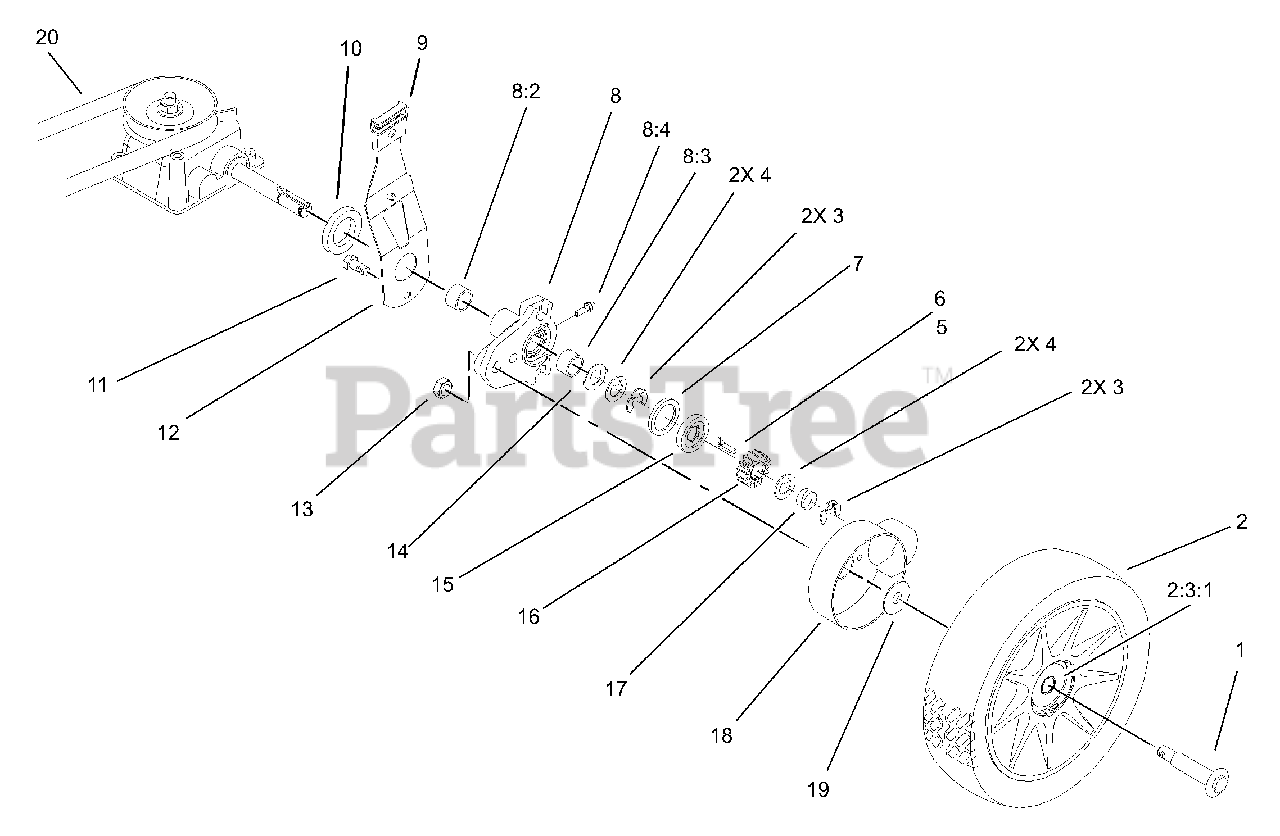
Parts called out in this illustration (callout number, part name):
1	Bolt-Shoulder
2	Wheel & Tire ASM
3	Klipring-Locking
4	Washer-Thrust, Keyed
5	Key-Rocking, LH
7	Ring-Friction
8	Rear Height Adjustment Arm ASM
8:4	Fitting-Grease
9	Knob-Lever, Height Adjustment
10	Spacer-Axle Shaft
11	Screw-HWH
12	Rear Spring Arm ASM
14	Washer-Arm, Pivot
15	Washer-Clutch
16	Gear-Pinion
17	Spring-Compression
18	Cover-Wheel
19	Washer-Stepped
